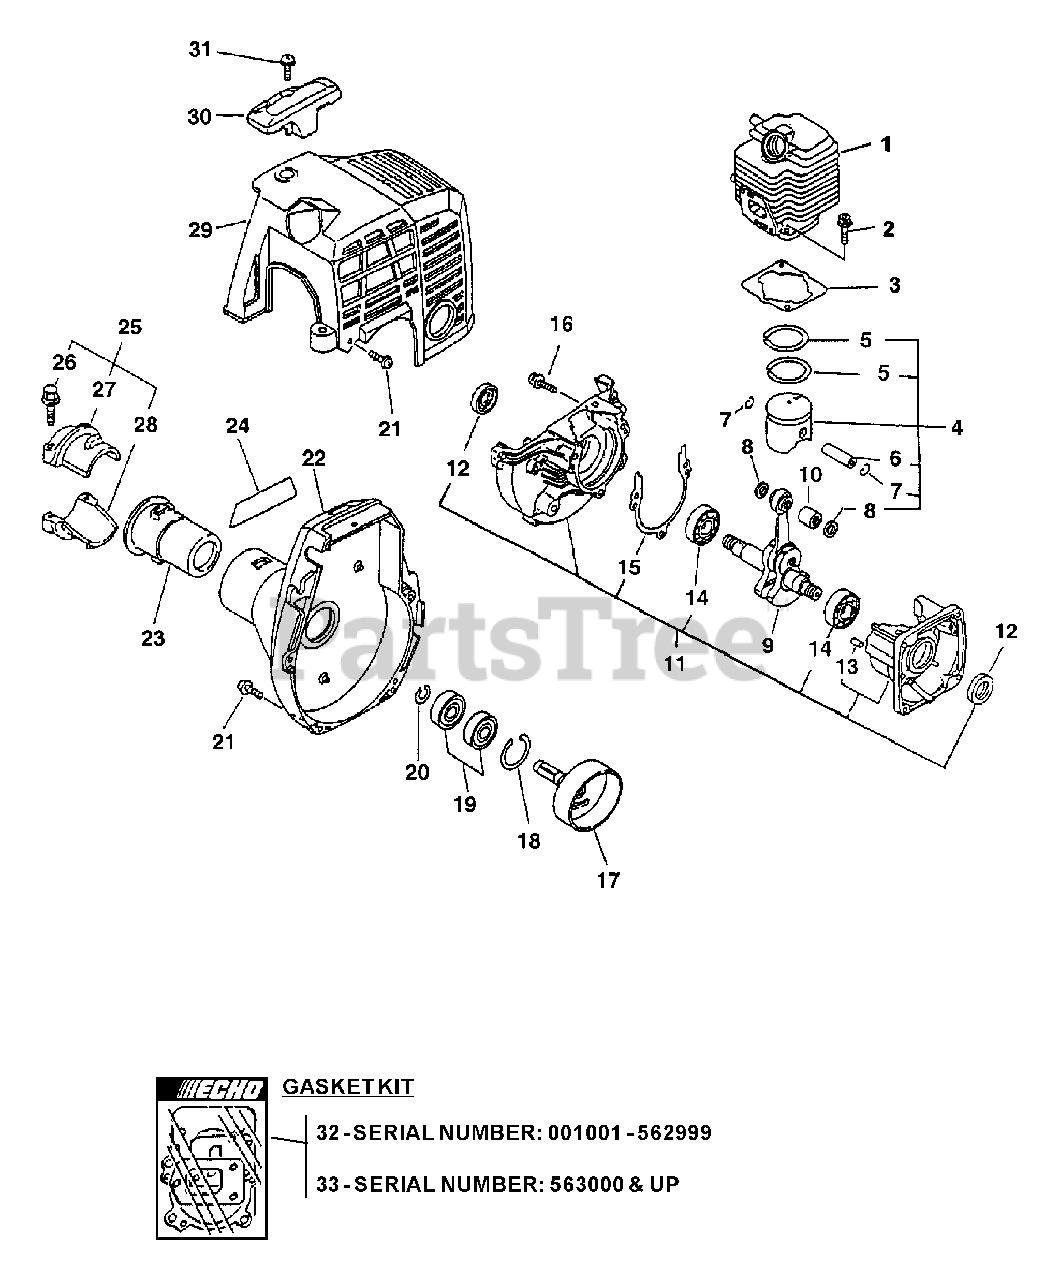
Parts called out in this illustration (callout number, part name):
1	CYLINDER
2	BOLT 5×22
3	GASKET, CYLINDER
4	PISTON KIT
5	RING, PISTON
6	PIN, PISTON 8
7	RING, SNAP
8	WASHER, THRUST
9	CRANKSHAFT ASSY
10	BEARING, NEEDLE
11	CRANKCASE KIT
12	SEAL, OIL 12
13	PIN, LOCATING 4
14	BEARING, BALL - 6201 C3
15	GASKET, CYLINDER
16	BOLT 5×28
17	DRUM, CLUTCH
18	RING, SNAP 28
19	BEARING, BALL 6001
20	RING, RETAINING - 12
21	BOLT 4×16
22	COVER ASSY, FAN
23	CUSHION Ø25
24	LABEL, MODEL
25	RETAINER KIT
26	BOLT - 5×25
27	HOLDER, MAIN PIPE - UPPER
28	HOLDER - LOWER
29	COVER, ENGINE
30	GUARD, TOP
31	SCREW 5×16
32	GASKET KIT
33	GASKET KIT
